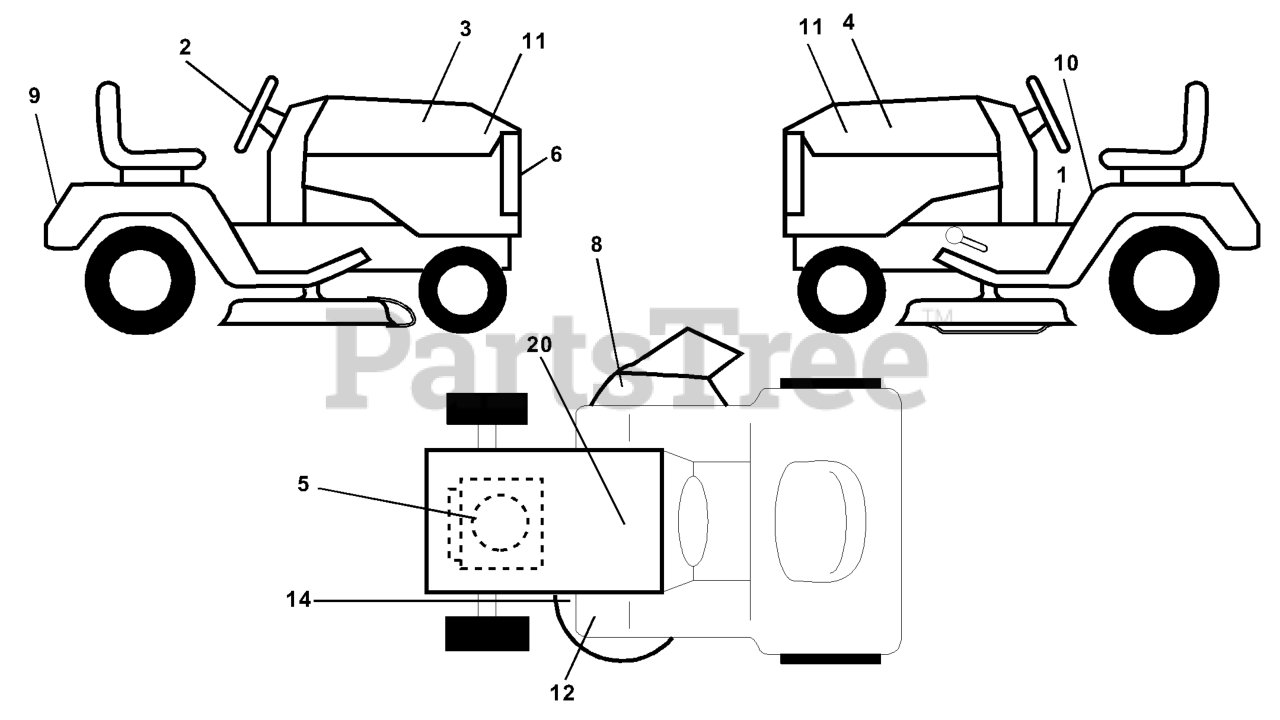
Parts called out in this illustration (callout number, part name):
2	DECAL.WHEEL.STEERING.HUSQ.PERM
3	HOOD DECAL
4	HOOD DECAL
5	DECAL ENGINE
6	DECAL.GRILLE.HUSQ
8	DECAL.WARN.KEEP.HAND.AWAY
9	DECAL, FENDER
10	DECAL FENDER DANGER
11	DECAL HOOD
12	DECAL CLUTCH/BRAKE
14	DECAL V-BELT SCHEMATIC
20	DECAL BTRY SYMBOLS
